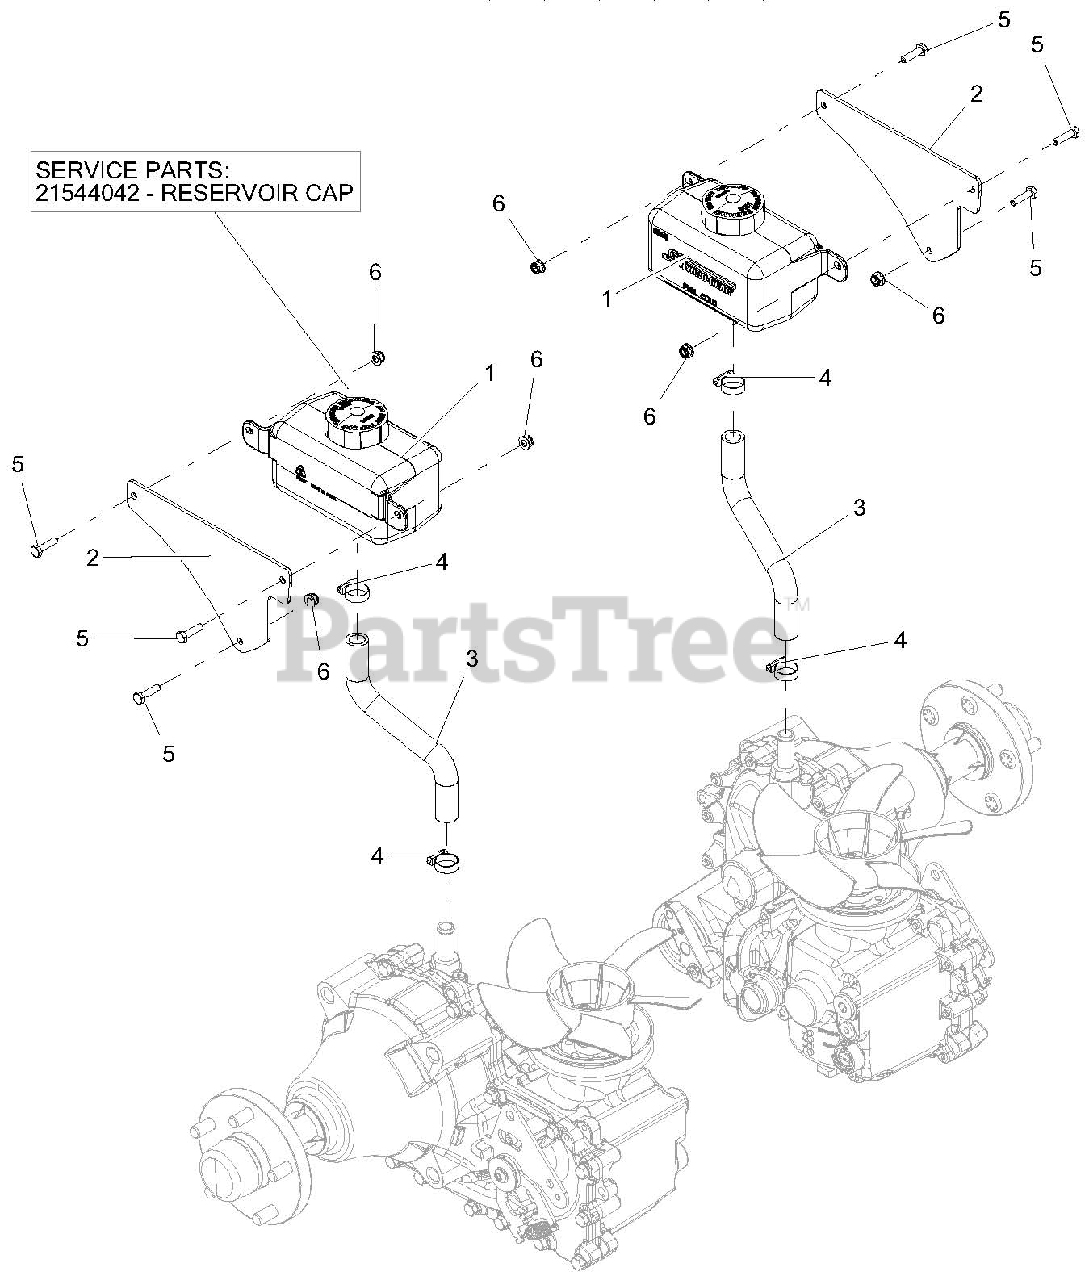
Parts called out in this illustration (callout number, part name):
1	TANK, HYD 1000ML
1	RESERVOIR CAP
2	PLATE, HYDRO OVERFLOW TANK MTG
3	HOSE, HYDRO OVERFLOW
4	CLAMP, .88 DIA HOSE
5	BLT-HEX .25-20X1.00 GR5 YWZC
6	NUT-LK-NYL-FLG .25-20 YWZC
